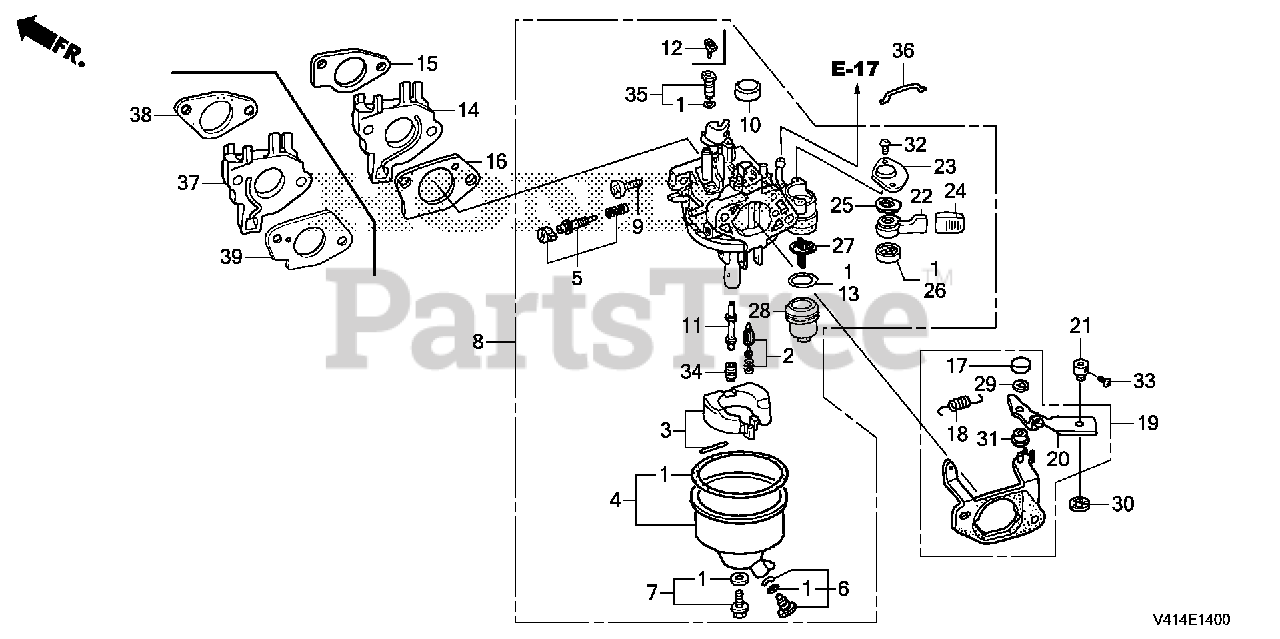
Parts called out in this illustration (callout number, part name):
1	GASKET SET
2	VALVE SET, FLOAT
4	CHAMBER SET, FLOAT
5	SCREW SET, PILOT
6	SCREW SET, DRAIN
8	CARBURETOR ASSY. (BE48F A)
9	SCREW, THROTTLE STOP
10	CAP, CHOKE DUST
11	NOZZLE, MAIN
12	COLLAR, SETTING
13	GASKET, FUEL STRAINER CUP
14	INSULATOR, CARBURETOR
15	GASKET, CARBURETOR INSULATOR
16	GASKET, CARBURETOR
17	CAP, CHOKE LEVER
18	SPRING, THROTTLE RETURN
19	STAY ASSY., CHOKE CONTROL (REMOTE)
20	LEVER, CHOKE
21	HOLDER, WIRE
22	LEVER, PETCOCK
23	PLATE, LEVER SETTING
24	CAP, LEVER
25	SPRING, PETCOCK LEVER
26	GASKET, PETCOCK
27	FILTER, CUP
28	CUP, FUEL STRAINER
29	E-RING (4MM)
30	CIRCLIP (5MM)
31	BUSH, CHOKE LEVER
32	SCREW, PAN (3X6)
33	SCREW, PAN (4X6)
34	JET, MAIN (#95)
34	JET, MAIN (#100)
34	JET, MAIN (#102)
35	JET SET, PILOT (#45)
36	ROD, CHOKE
